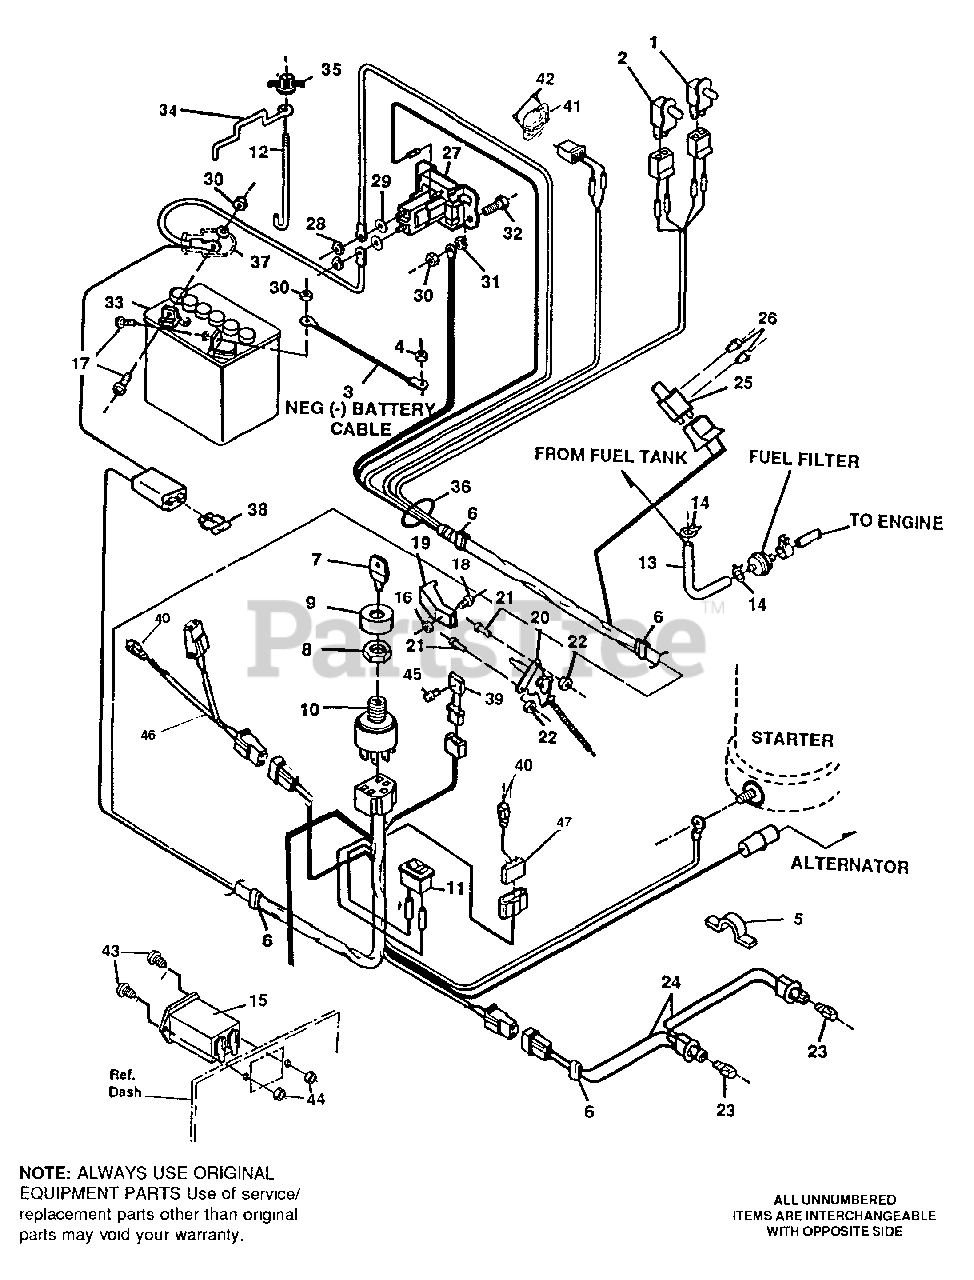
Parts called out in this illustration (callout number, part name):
1	Seat Switch
2	Deck Safety Switch
3	Cable, Battery, Negative
4	Nut, Hx, Keps, 5/16-18 Thd.
5	Press Clip
6	Tie Cable
7	Key, Ignition Switch
8	Nut, Switch
9	Boot, Switch
10	Switch, Ignition
11	Switch, Light
12	Rod, Battery Hold-Down
13	Gas Line, 13-1/2" (cut to length)
14	Clamp, Gas Line
15	Minature Hour Meter
16	Nut, Hex, #8-32 Thd.
17	Screw, 1 /4-20 x .63
18	Screw, Ph Pn, #8-32 x 3/8 In.
19	Knob, Throttle Control
20	Throttle Control
21	Screw, #10-24 X 5/8 In.
22	Nut, Hx, Nylon Lock, #10-24 Thd.
23	Bulb Headlamp
24	Assembly, Light Wire
26	Screw, Pn Hd, Tap #12 x 112 In.
27	Solenoid
28	Nut, Hx 5/16-24 Thd.
29	Washer, Lock 5/16 In.
30	Nut, Hx, Keps, 1/4-20 Thd.
31	Nut, Hx, Ctrlk, 1/4-20 Thd.
32	Screw, 1/4-20 X 3/4 In.
34	Bracket, Battery Hold-Down
36	Wiring Harness
37	Boot, Rubber (Battery Cable)
38	Fuse, 15A-32V
39	Low Voltage Sensor
40	Bulb Indicator
41	Seat Switch
42	Screw, 1/4-20 x .38
43	Screw, #6-32 x 1 /2 1 n.
44	Nut, #6-32 Thd.
45	Screw, Plastite
46	Low Fuel Wire
47	Lamp holder 4 Pin
